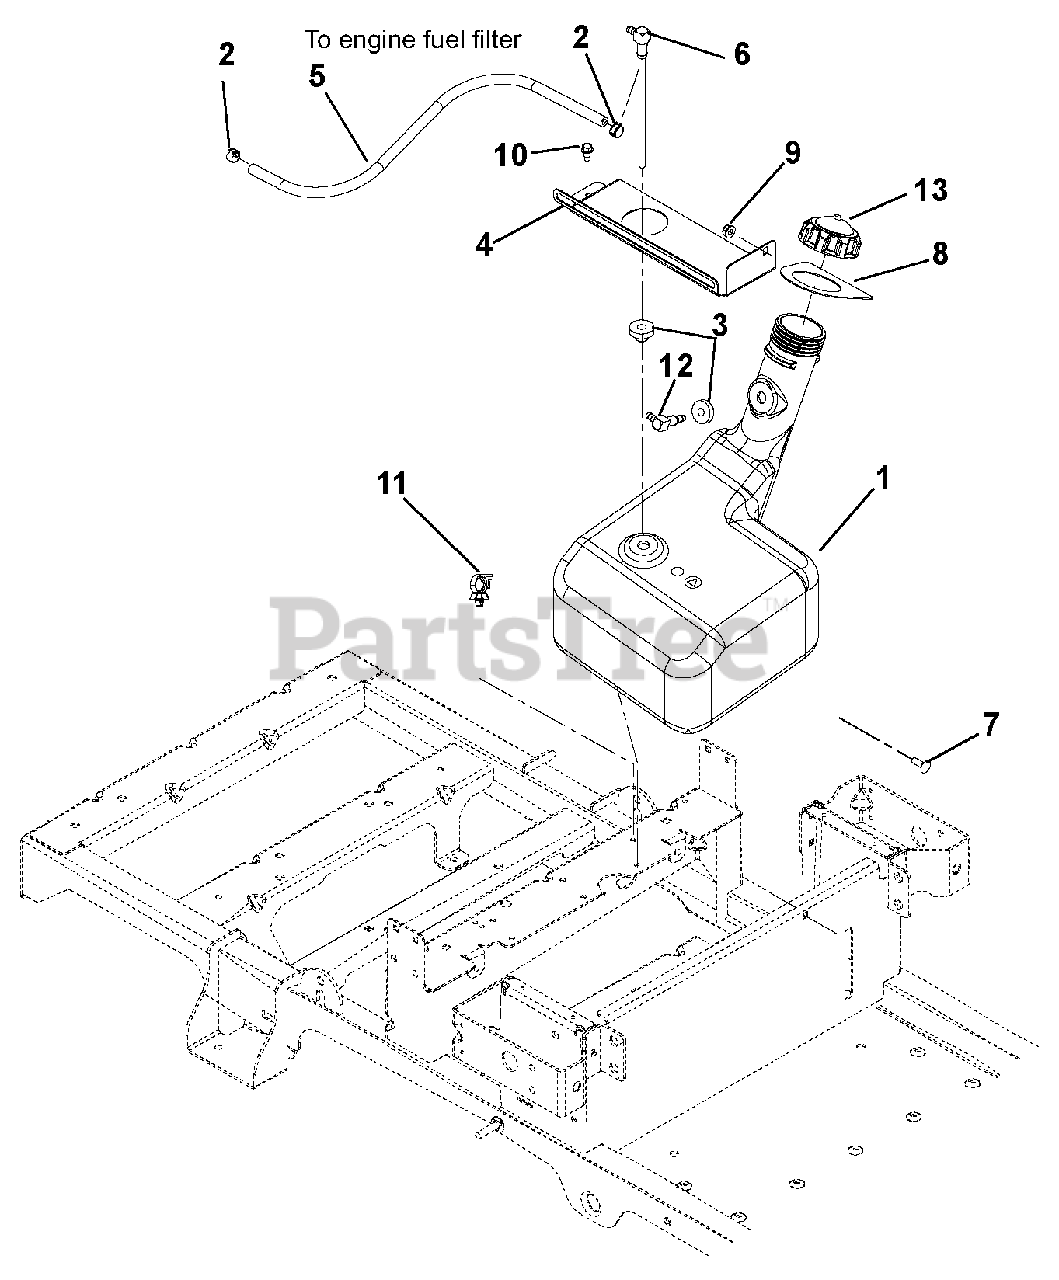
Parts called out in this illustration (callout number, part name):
1	Tank, Fuel with Vent Port
2	Clamp, Fuel Line
4	Bracket, Tank Strap
5	Hose, .25 Low Perm Gas (as required)
6	Assembly, Fuel Pickup
7	Bolt, Round Head Square Neck .25-20 x .75
8	Seal, Tank Neck
9	Nut, .25-20 Nyloc Flange
10	Screw, Tapping .25-20 x .50 Hex Washer Head
11	Wire Clip
12	Fitting, 90 Degree Fuel Plastic
13	Fuel Cap, 225 CARB with 12" THTR
